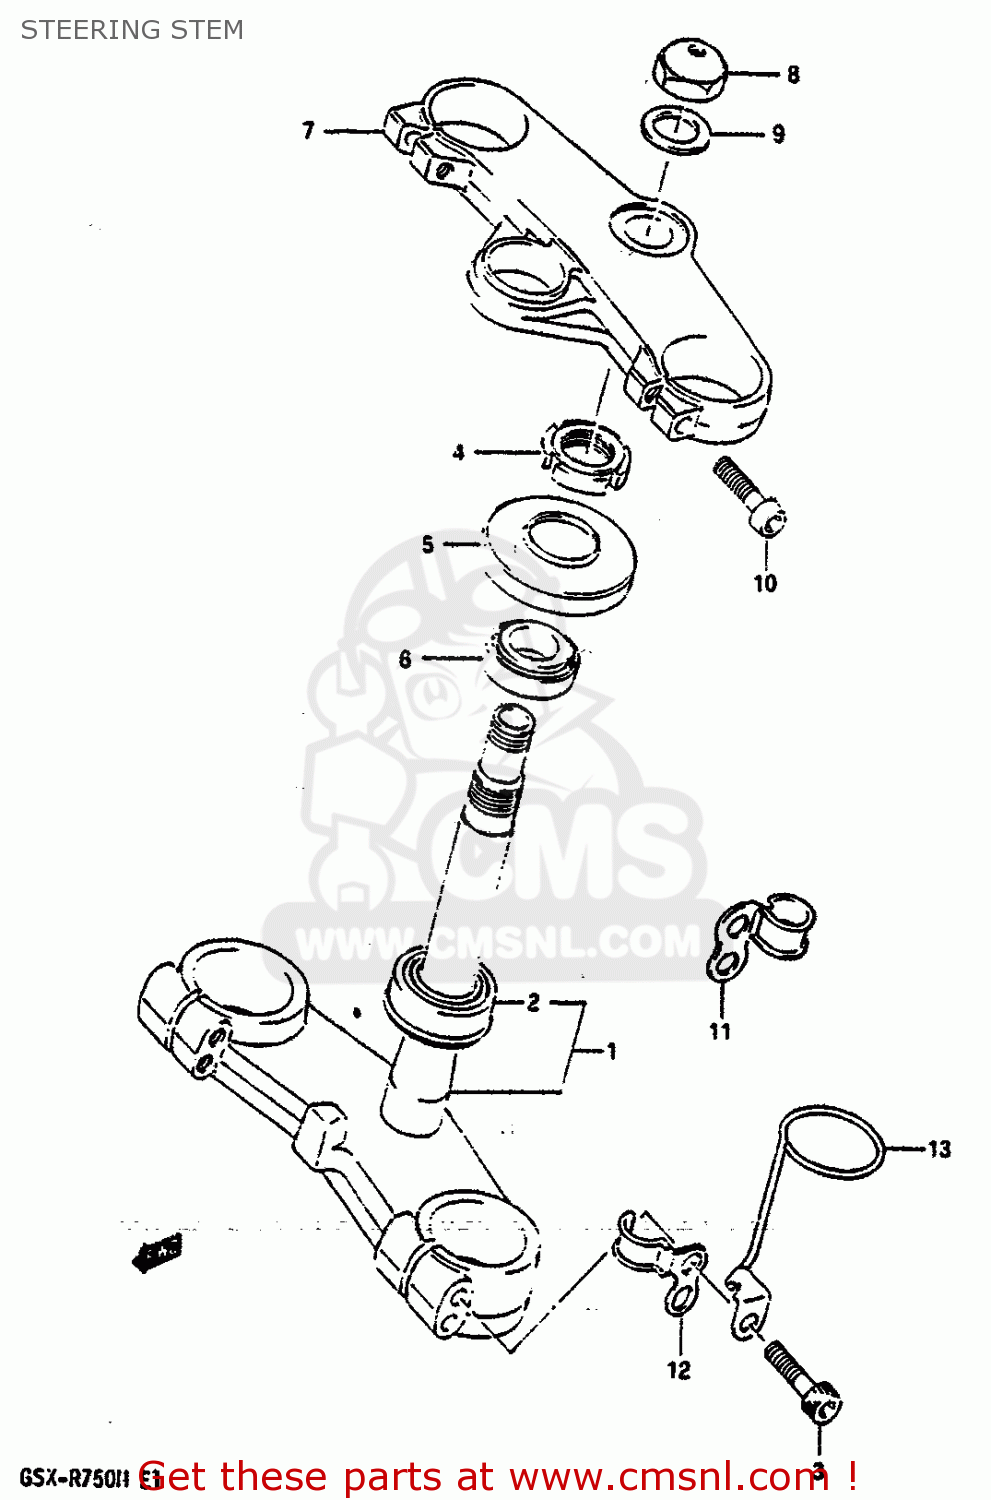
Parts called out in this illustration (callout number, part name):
1	STEM,STEERING
2	BEARING(30X55X17)
3	BOLT 10X45
4	NUT,STEERING STEM(25X44X10)
5	SEAL OIL
6	TAPER,ROLLER BEARING
7	HEAD,STEERING STEM
8	NUT,STEM HEAD
9	WASHER
10	BOLT,UPR
11	GUIDE,SPEEDOMETER CABLE
12	CLAMP,CLUTCH CABLE
13	HOLDER,STEERING DAMPER
